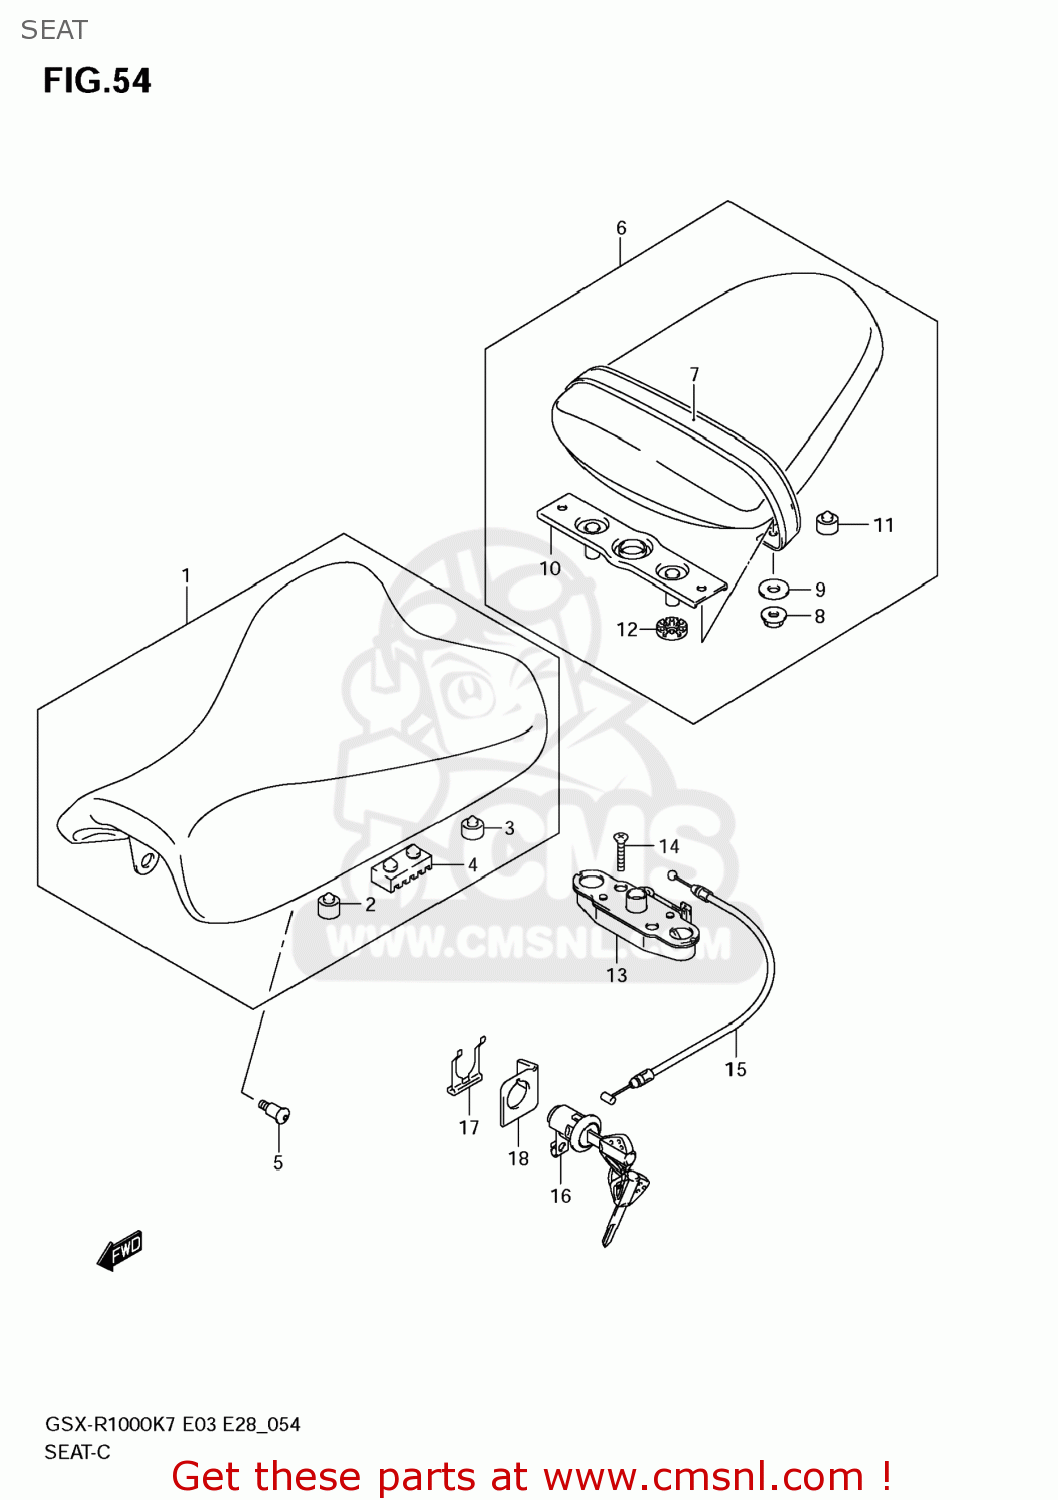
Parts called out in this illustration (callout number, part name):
1	SEAT ASSY
2	CUSHION
3	CUSHION
4	CUSHION,SIDE
5	SCREW(6X16)
6	SEAT ASSY,PILLION
7	BAND ASSY,SEAT
8	NUT
9	WASHER(6.5X20X1.6)
10	STRIKER
11	CUSHION
12	CUSHION
13	BRACKET,SEAT SUPPORT,RIGHT
14	SCREW
15	CABLE,SEAT LOCK
16	LOCK SET,SEAT
17	PLATE,SEAT LOCK ASSY
18	GUIDE,SEAT LOCK CABLE
